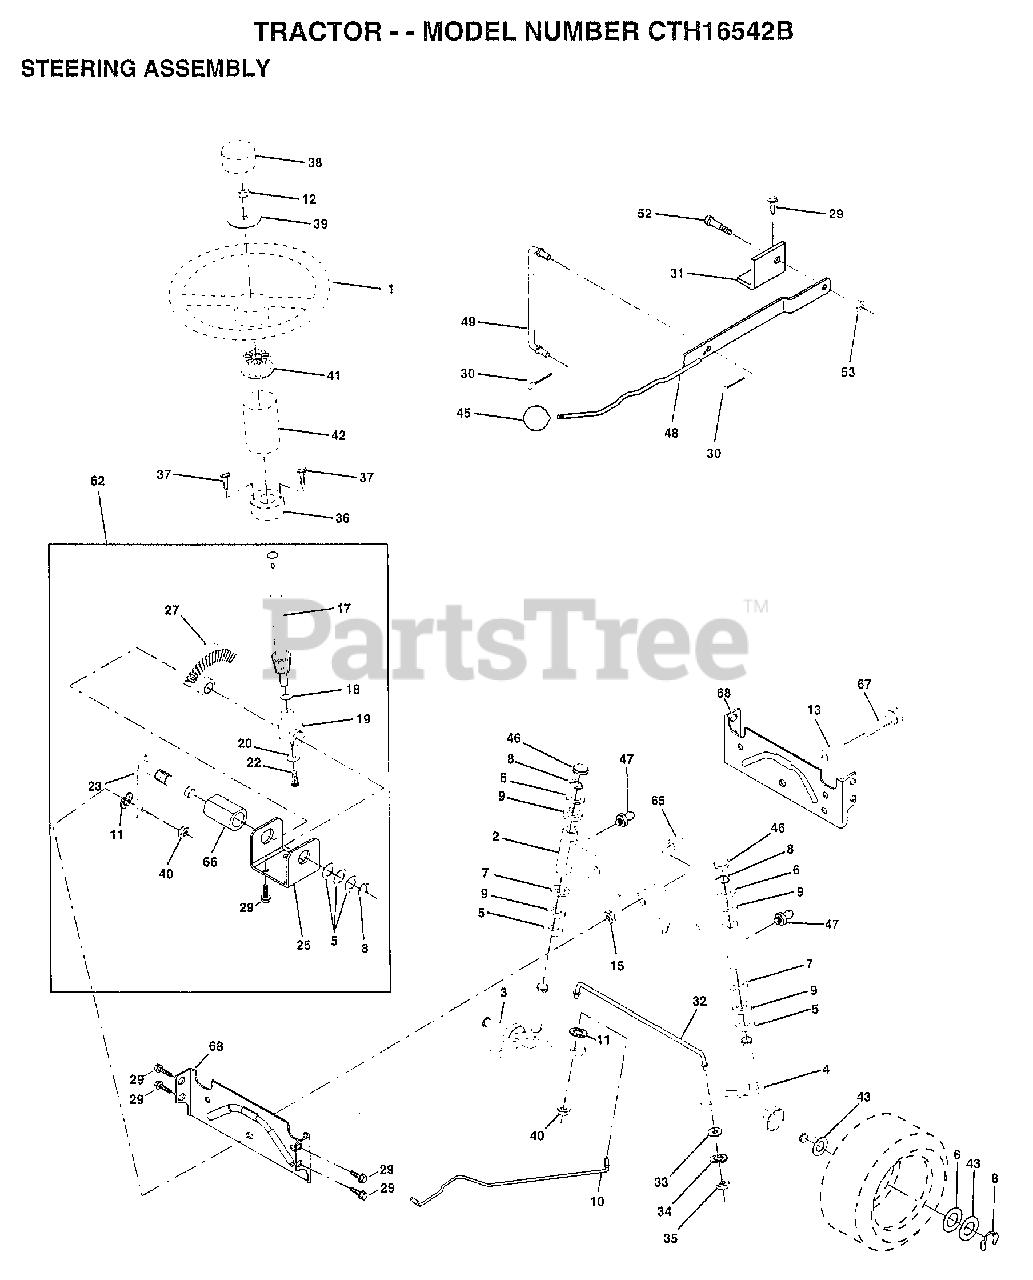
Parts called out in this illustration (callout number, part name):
1	WHEEL STR AYP BLK
2	AXLE ASM
3	SPINDLE.ASM.LH
4	"SPINDLE ASM,RH"
5	WASHER .T
6	WASHER
7	WASHER
8	RING
9	COL. SRTG. BEAR.
10	DRAGLINK-STAMPED
11	LOCKWASHER
13	BEARING AXLE
15	"NUT-LOC,FLANGE LT"
17	SHAFT ASM STEERNG
18	THRUST WASHER
19	SUPPORT.SHAFT
22	SCREW HEX SOC1/4-
25	BRKT-STEERING
27	GEAR SECTOR
29	SCREW
30	COTTER PIN
31	BRKT.PVT.MAN.LVR.
32	ROD.TIE.19.75
33	WASHER M
34	LOCKWASHER
35	NUT.LOCK.5/16-24
36	BUSHING.STRG.3/4
37	"SCREW-TT,10-32 FL"
38	CAP STEER AYP
39	WASHER
40	GRIPCO NUT
41	ADAPTER LT
42	BOOT SHAFT STEER
45	KNOB T (1/2-HOLE)
46	CAP
47	ZERK M
48	LEVER.ASM.CLUTCH
49	LINK CLTCH W/NUTS
52	"BOLT, SHOULDER LT"
62	KIT STEERING ASM
65	SPACER AXLE
66	"BEARING-ARM,PITMA"
67	BOLT
68	BRACE AXLE
